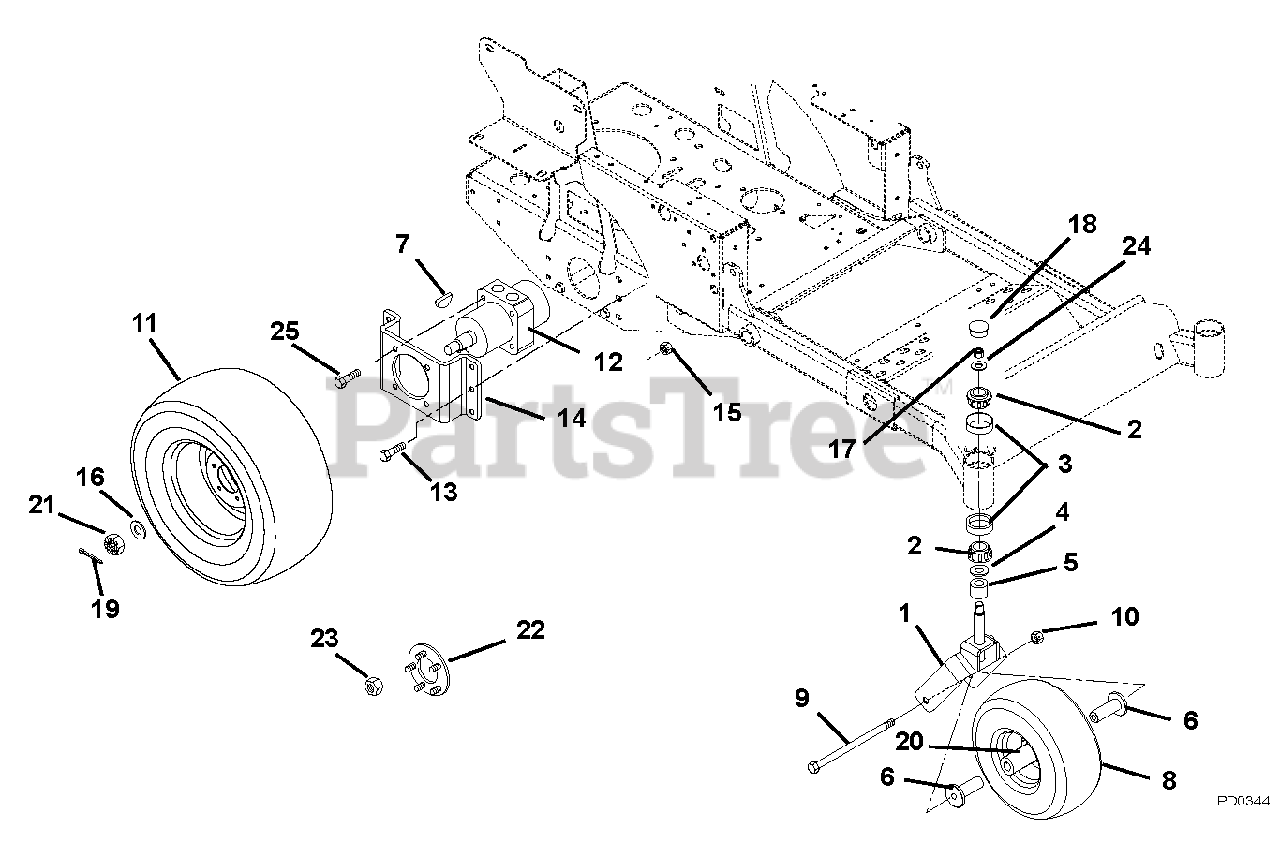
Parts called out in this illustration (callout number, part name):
1	Weldment, Front Fork
2	Bearing, Cone with Grease, 1.0 x .58
3	Bearing, Cup 1.980 x .420
4	Bearing Seal 1.5 x 2 x .18
5	Spacer, PM, 1.03 I.D. x 1.5 O.D. x .375
6	Spacer, Wheel
7	Key, Woodruff .31 x 1.00 (Included with Item 12)
8	Tire/Wheel Assembly, 13 x 5.00-6
8	Tire, 13 x 5.00-6
9	Bolt, Hex .50-13 x 7.50 Grade 5
10	Nut, Nyloc Flange .50-13
11	Tire/Wheel Assembly, 21 x 7.00-10
11	Tire, 21 x 7.00-10
12	Motor, Hydraulic Wheel
13	Bolt, Hex .38-16 x 1.00 Grade 5
14	Bracket, Wheel Motor
15	Nut, Nyloc Flange 3/8-16
16	Washer, Flat Steel .755 x 1.375 x .062
17	Nut, Center Lock Jam .75-16
18	Cap, Dust
19	Pin-Cotter .09 x 1.25 Extended Prong Square Cut
20	Bearing, 25MM I.D. x 52MM OD x 15MM (Included with item 8)
21	Nut, Hex .75-20
22	Assembly, Service Hub with Studs
23	Wheel Nut .437-20
24	Washer, Flat, Steel .880 x 1.250 x .062
25	Bolt, Hex .38-16 x 1.00 Grade 8 Epoxy 30
